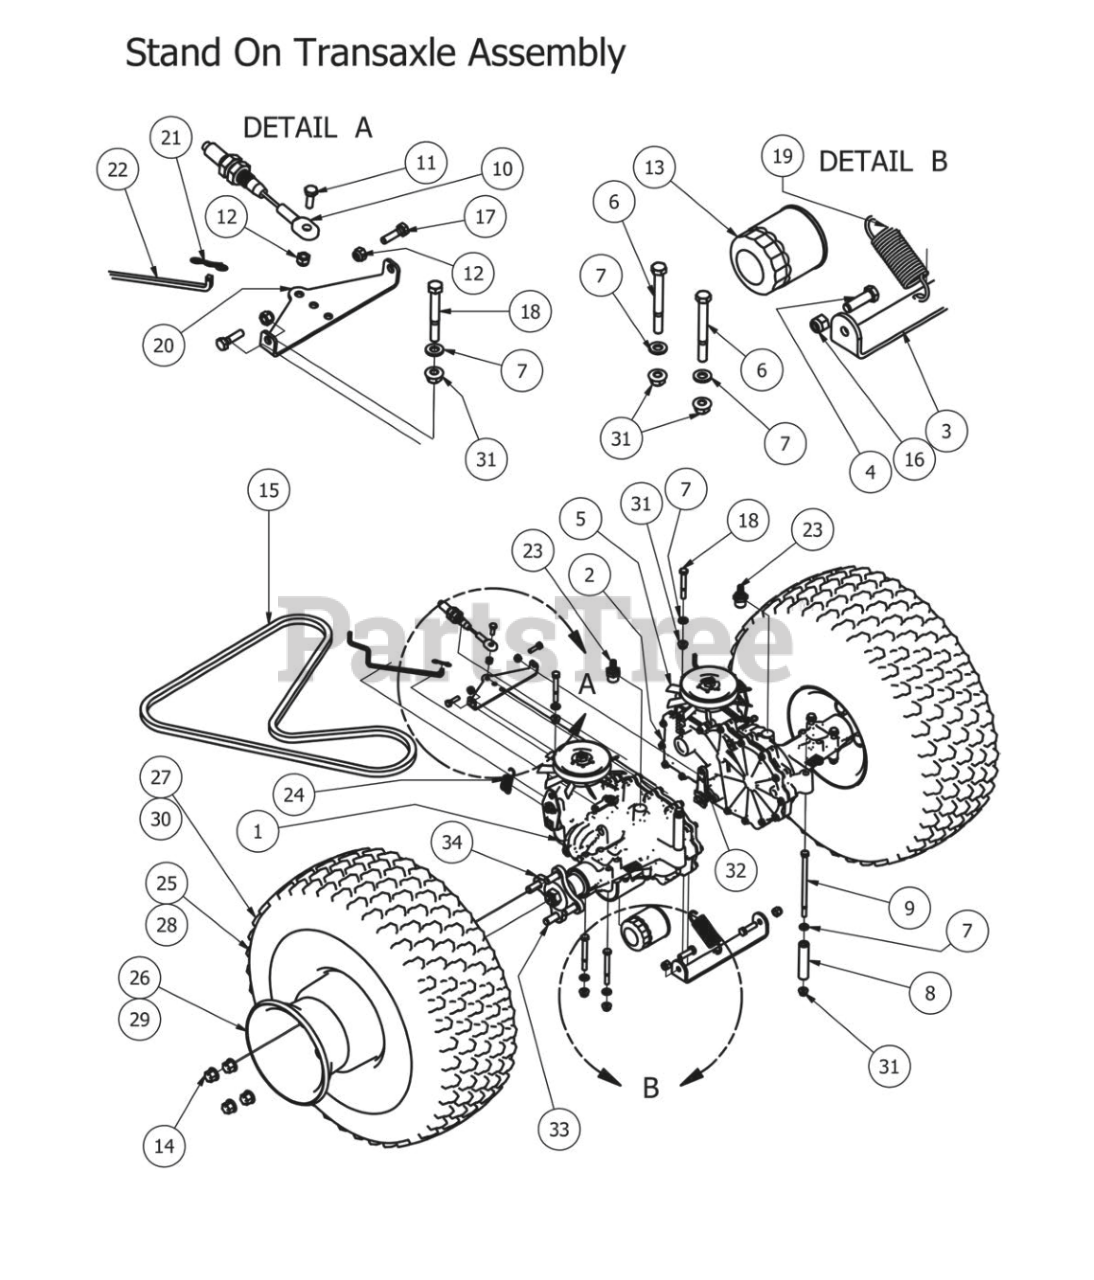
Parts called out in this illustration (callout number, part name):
1	Left 3400 IZT for CZT
2	Right 3400 IZT for CZT
3	Crossover Bar for ZT
4	3/8" x2" Hex Bolt
5	Fan/Pulley Kit For CZT
6	5/16" x 3" Hex Bolt
7	5/16" Flat Washer
8	3 1/4" Spacer
9	5/16" x 6" Bolt
10	Brake Cable-Bandit Stand On
11	1/4" x 3/4" Hex Bolt
12	1/4" Nylock Nut
13	Transaxle Hydro Filter
14	Acorn Lug Nut
16	3/8 Nylock Nut
17	1/4-20 x 1 GR 5 hex bolt zinc
18	5/16" x 2 1/2" Bolt
20	Brake Bracket
22	MZ Brake Release Bar
23	45 degree fitting
24	Spring for Stand On Models
25	23 x 10.50 -12 Assembly W/Negative Offset Wheel
26	12 Orange Wheel
27	23 x 10.50 -12 Tire
28	23 x 8.50-12 Tire & Wheel Assembly (48" Deck only)
29	23 x 8.50 (Wheel 48" Deck only)
30	23 x 8.50 -12 Tire (48" Deck only)
31	5/16" Nylon Flange Nut
32	Transaxle Brake Lever
33	Transaxle Wheel Studs
34	ZT Transaxle Hub
